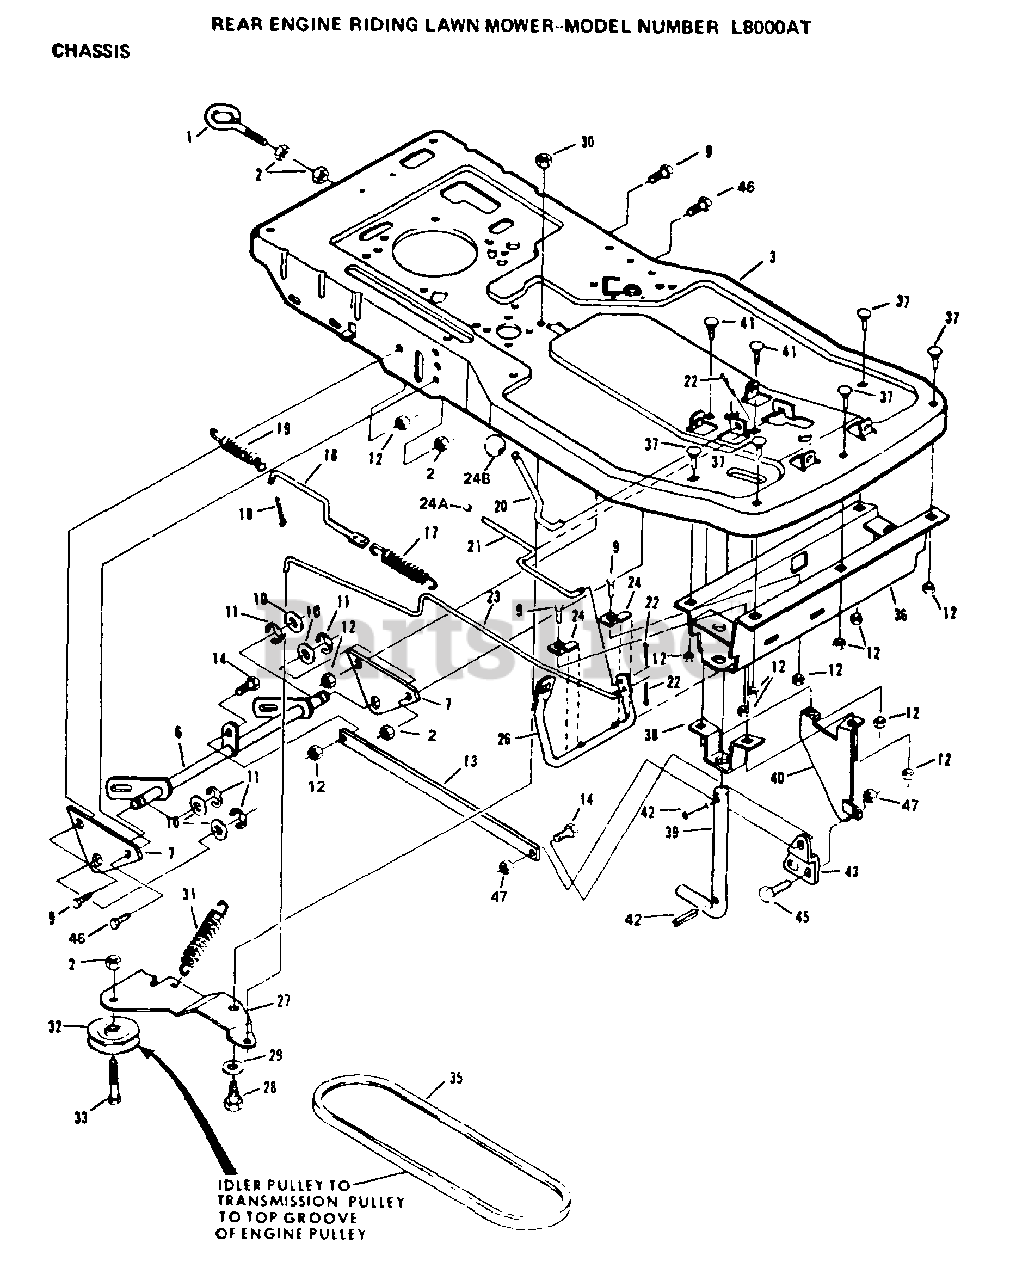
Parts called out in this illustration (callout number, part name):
1	TOW HITCH - EYEBOLT
9	BOLT
10	WASHER LT
13	PARALLEL BAR
20	LIFTER HANDLE
22	COTTER PIN
24A	PLUNGER CAP T
30	NUT
31	IDLER SPRING
32	IDLER PULLEY RER
35	V BELT T (L439)
37	BOLT
41	BOLT
42	DRIVELOKPINTYPE
47	NUT
